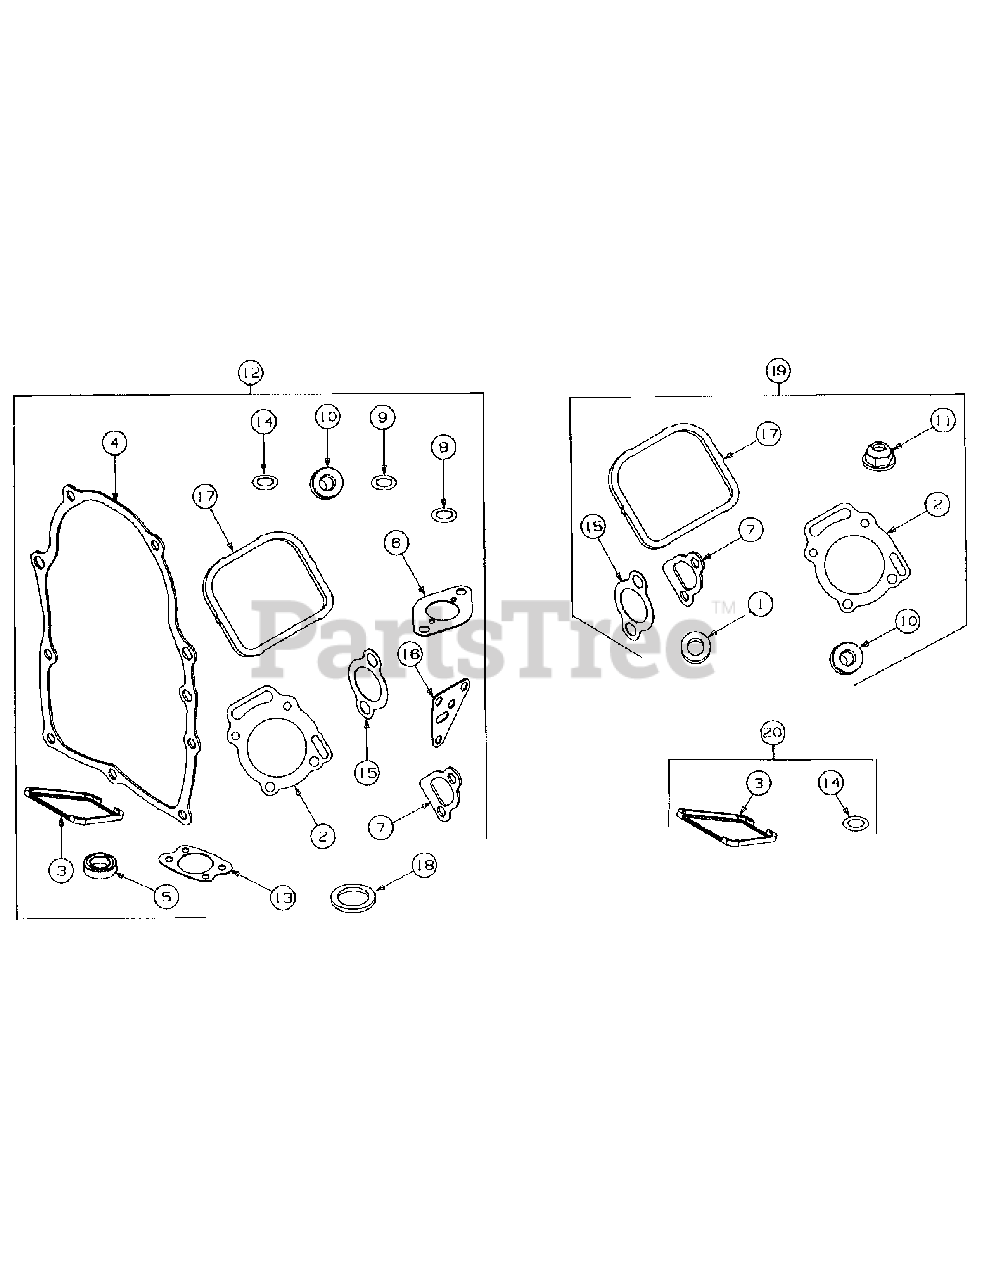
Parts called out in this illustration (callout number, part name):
1	Washer, Cylinder Head
2	Gasket, Cylinder Head
3	Gasket, Breather
4	Gasket, Crankcase Cover
5	Seal, Oil
6	Gasket, Carburetor
7	Gasket, Intake Manifold
8	O-Ring
9	O-Ring
10	Washer, Valve Cover
11	Nut, Nylock
12	Gasket, Set
13	Gasket, Air Cleaner
14	Seal, Breather Screw
15	Gasket, Exhaust Manifold
16	Gasket, Oil Filter Adapter
17	Gasket, Valve Cover
18	Seal, Oil
19	Overhaul Kit
20	Gasket Set, Breather
